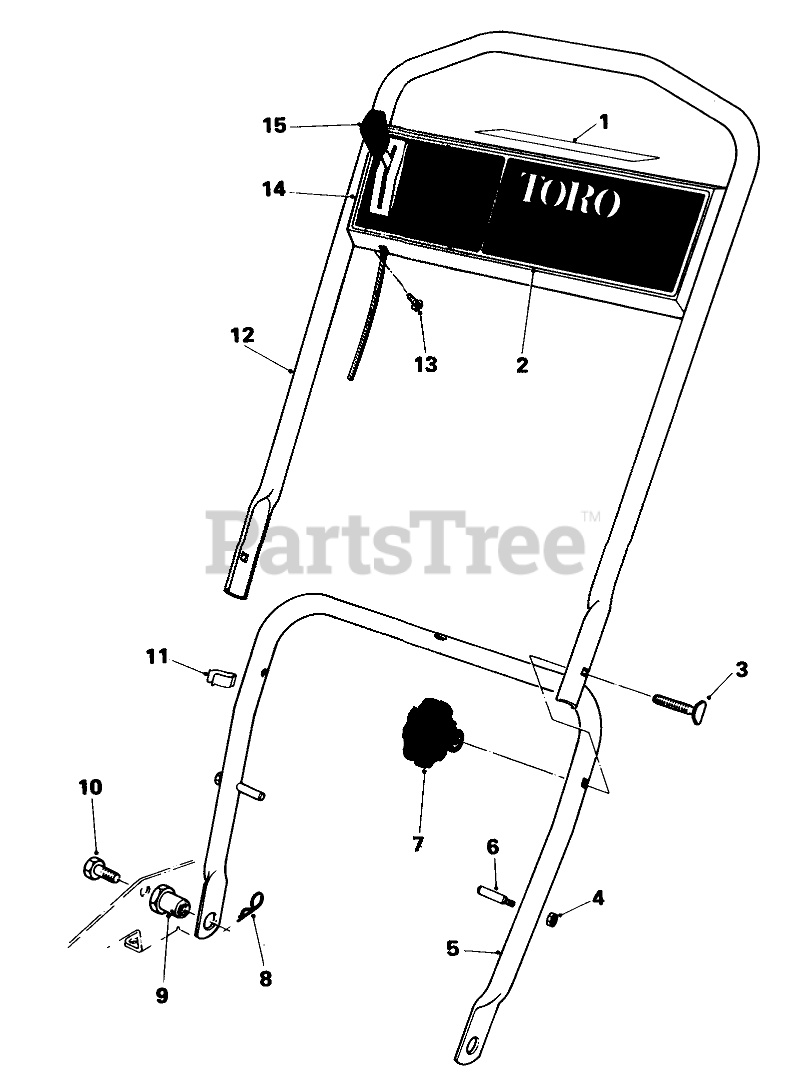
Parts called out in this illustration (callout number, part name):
1	Decal-Instruction
2	Decal-Control Plate
3	SCREW-HANDLE
4	Nut
5	Handle-Lower
6	HANDLE PIN
8	PIN-COTTER, HAIR
9	HANDLE PIVOT NUT
10	SCREW-HH
12	UPPER HANDLE
13	SCREW-HWHTF
14	Control Plate
15	Throttle Control
